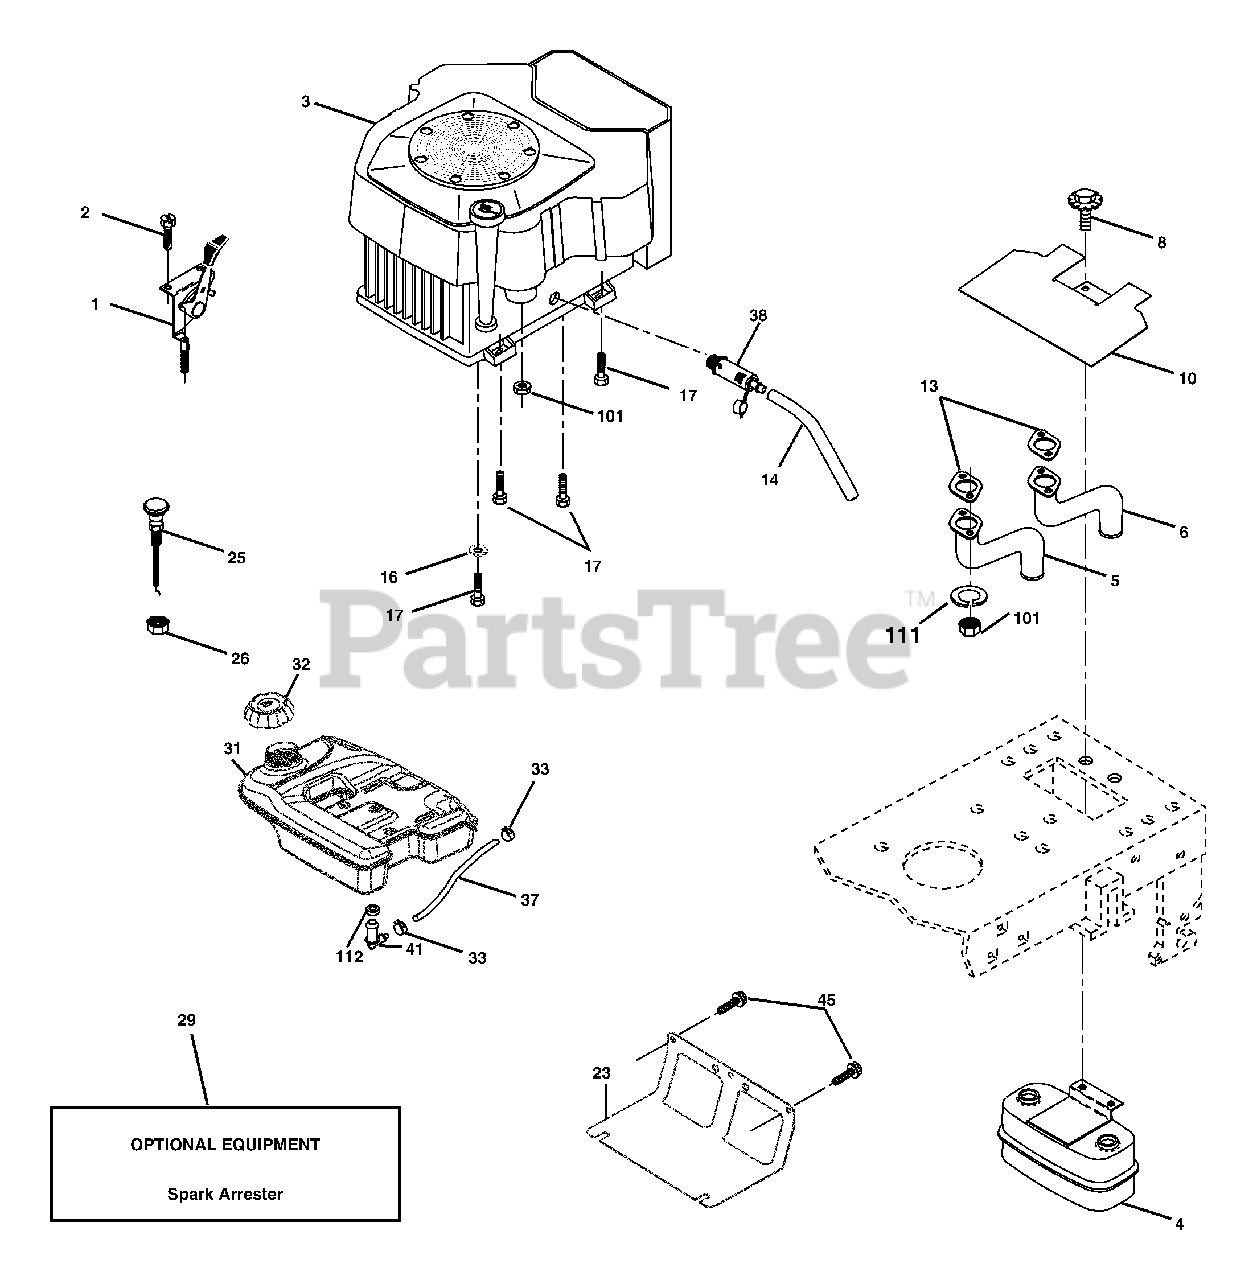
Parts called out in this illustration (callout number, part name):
1	Control Throttle
2	Screw Hw Hd Hi-Lo #13-16 x 3/4
4	Muffler Asm Twin Lo-Tone
5	Pipe Exhaust LH
6	Pipe Exhaust RH
8	Bolt 5/16-18 UNC x 3/4 w/Sems
10	Shield Heat Muffler
13	Muffler Gasket
14	Tube Drain Oil Easy
17	Screw Thdrol 3/8-16 x 1-1/2
23	Shield Heat
25	Choke Control
26	Nut, Keps 3/8-24 UNF
29	Kit Spark Arrestor (Flat Scrn)
31	Tank Fuel 4.0 Rear
32	Cap Asm Fuel
33	Clamp Hose Black
37	Line Fuel
38	Plug Drain Oil
41	Stem Tank Fuel
45	Screw Hexwsh Thdr 3/8-16 x 3/4
101	Nut Flange
111	Washer Split
112	Bushing
